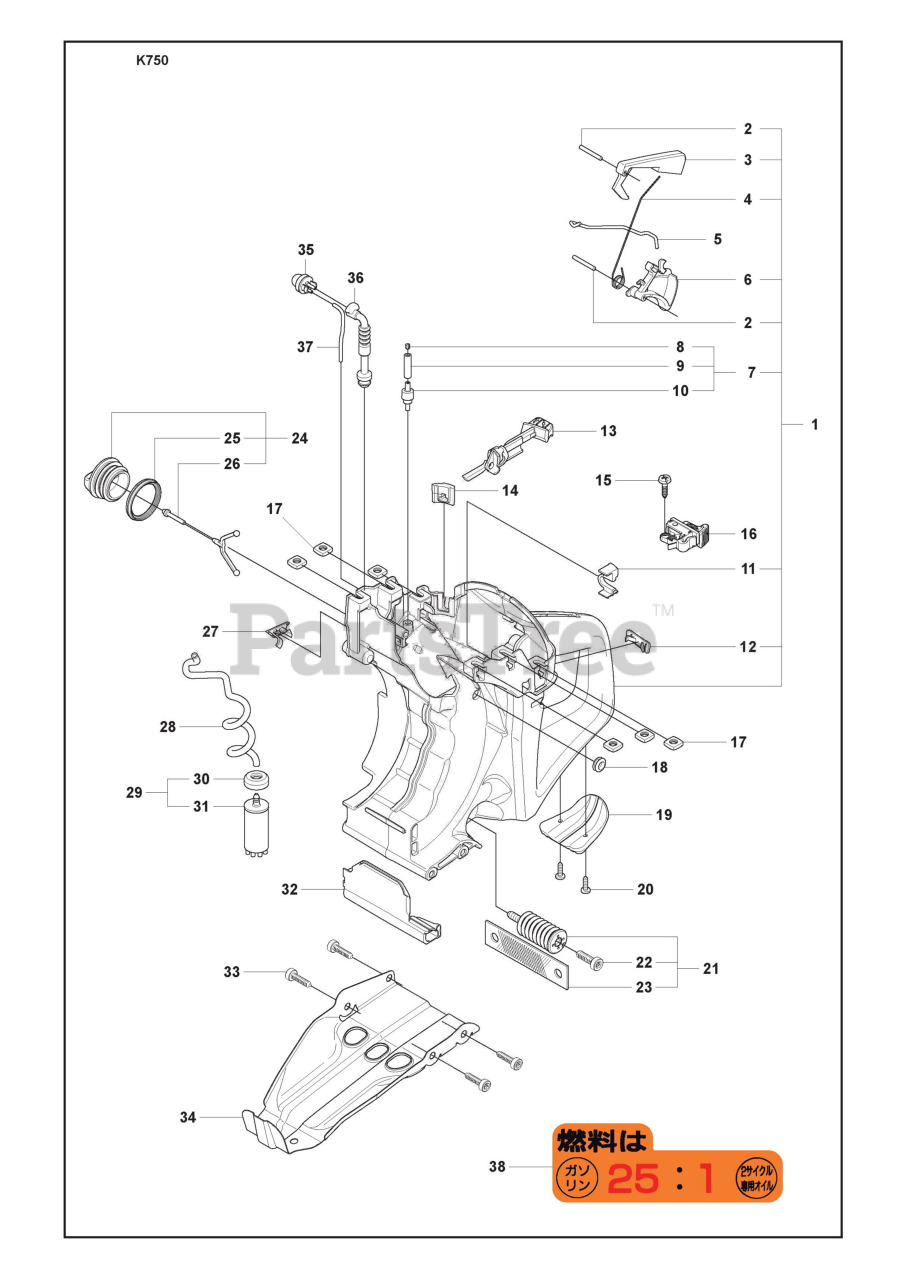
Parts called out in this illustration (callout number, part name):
1	FUEL TANK
2	PARALLEL PIN
3	THROTTLE LOCKOUT
4	SPRING
5	THROTTLE ROD
6	THROTTLE TRIGGER
7	TANK VENT ASSY
8	SINTER PLUG
13	CHOKE CONTROL
16	STOP SWITCH
18	CABLE GROMMET
19	GROUND SUPPORT
21	VIBRATION ABSORBER
24	TANK CAP ASSY
26	TANK CAP HOLDER
28	FUEL HOSE
29	FUEL FILTER
30	HOSE CLAMP
31	FUEL FILTER
32	HEAT SHIELD
34	BASE PLATE
35	PRIMER HOUSING
36	FUEL HOSE
37	FUEL HOSE
38	LABEL
